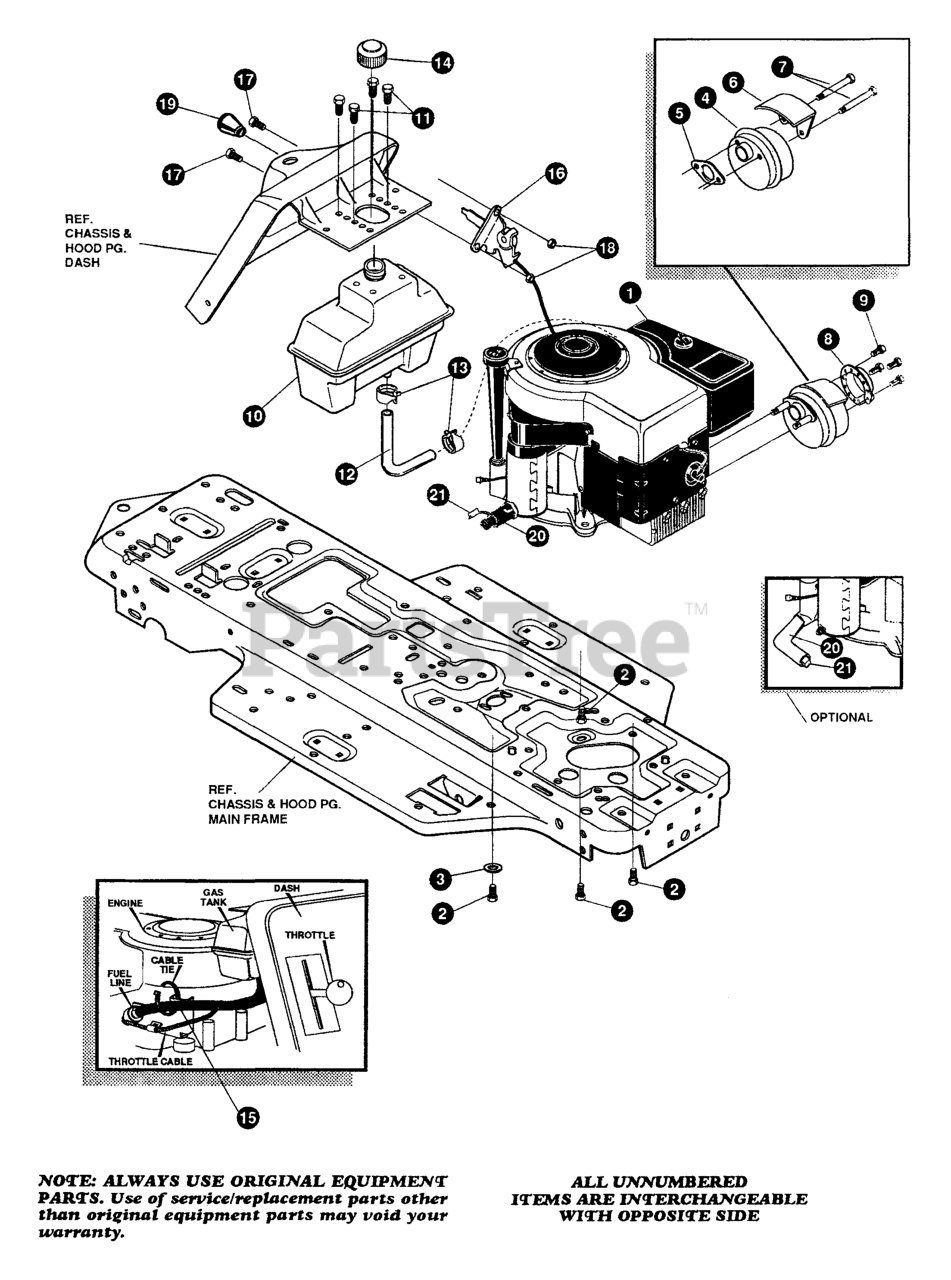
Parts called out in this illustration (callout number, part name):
2	SCREW, 3/8-16 X 1.25
3	WASHER, .384 X .69 X .04
4	MUFFLER, ROUND
5	GASKET, MUFFLER
6	SHIELD, HEAT
7	SCREW, 5/16-18 x 3.50
8	DEFLECTOR SIDE OUT
9	SCREW, #8-32 X .38
10	TANK, FUEL 1 GALLON
11	SCREW, .25 X .75 X .51
12	TUBING, .25 X .50 X BULK GAS LINE
13	CLAMP, FUEL LINE
14	CAP, GAS
15	TIE, CABLE BLACK
16	THROTTLE CONTROL
17	SCREW, 10-24 X .50
18	NUT, #10-24
19	KNOB, ROUND THROTTLE
20	NOT REQUIRED ON THIS UNIT
21	NOT REQUIRED ON THIS UNIT
